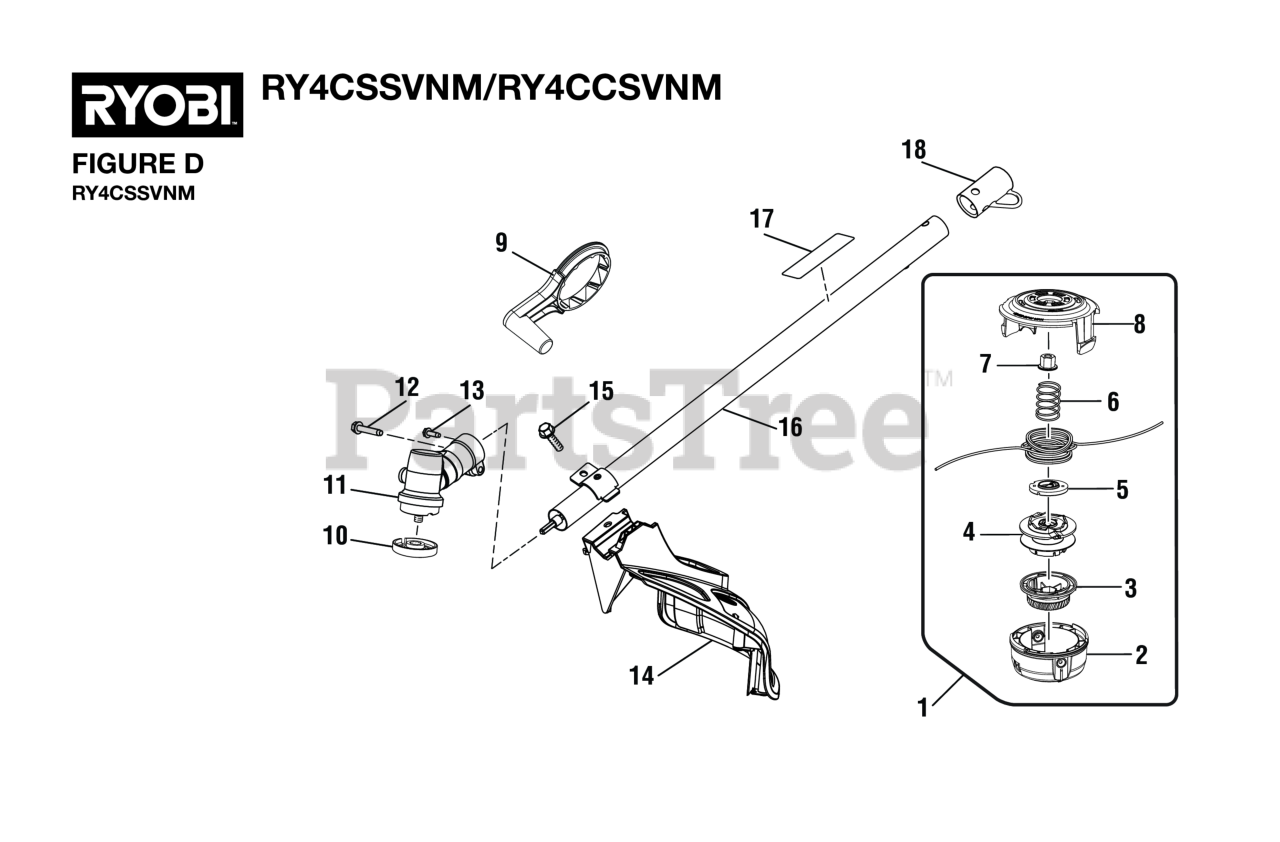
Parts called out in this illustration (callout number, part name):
1	Trimmer Head Assembly (.095)
2	Lower Housing
3	Bump Knob (Green)
4	Spool Assembly
5	String Guide
6	Compression Spring
7	Hex Nut (M8, Left Hand Threads)
8	Upper Housing
9	Crank Handle
10	FLANGED WASHER
11	Gear Case Assembly
12	Screw (1/4-20 x 1-1/4 in., Hex Washer Hd. S.T.)
13	Screw w/Washer (10-24 x 5/8 in., Hex Hd. T.F.)
14	Grass Deflector Assembly
15	SCREW (#1/4-20 X 1-1/4 in. HEX WASHER HD.)
16	Straight Shaft Assembly (Inc. Key Nos. 17-18)
17	Warning Icon Label
18	Hanger Cap
